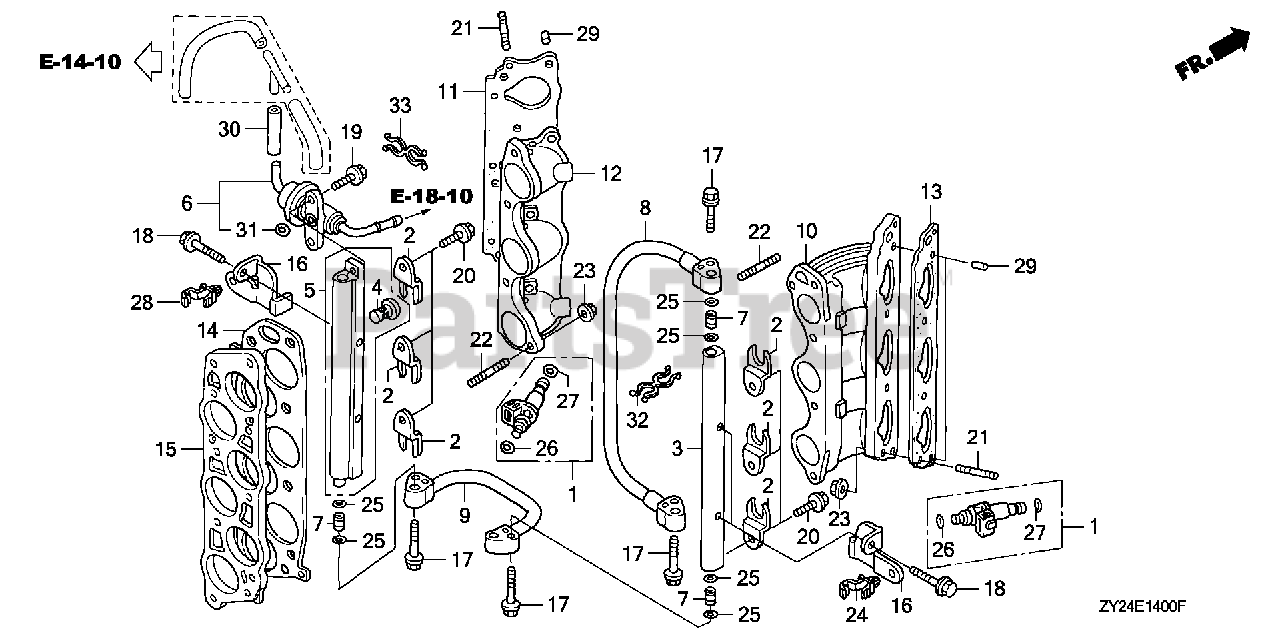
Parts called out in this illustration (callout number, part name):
1	INJECTOR ASSY., FUEL
2	CLIP, INJECTOR
3	PIPE, R. FUEL
4	MESH, FUEL FILTER
5	PIPE, L. FUEL
6	REGULATOR ASSY., PRESSURE
7	JOINT, FUEL PIPE
8	HOSE, FUEL
9	HOSE, FUEL JOINT
10	BASE, R. INJECTOR
11	GASKET, RR. INJECTOR BASE
11	GASKET, FR. INJECTOR BASE
12	BASE, L. INJECTOR
13	GASKET, FR. INJECTOR BASE
13	GASKET, RR. INJECTOR BASE
14	GASKET, IN. MANIFOLD
15	SPACER, IN. MANIFOLD
16	BRACKET, HARNESS CLIP A
17	BOLT, FLANGE (6X25)
18	BOLT, FLANGE (6X35)
19	BOLT, FLANGE (6X14)
20	BOLT, FLANGE (6X10)
21	BOLT, STUD (8X28)
22	BOLT, STUD (8X45)
23	NUT, FLANGE (8MM)
24	CLIP, WIRE HARNESS (10MM)
25	O-RING (7.8X1.9) (ARAI)
26	O-RING (7.47X3.6)
27	O-RING (7.45X3.61) (NOK)
28	CLIP, HARNESS (7MM)
29	PIN, DOWEL (10X12)
30	BULK HOSE, FUEL (3.5X3000) (3.5X50)
31	O-RING, PRESSURE REGULATOR
32	CLIP D, SPEEDOMETER CABLE
